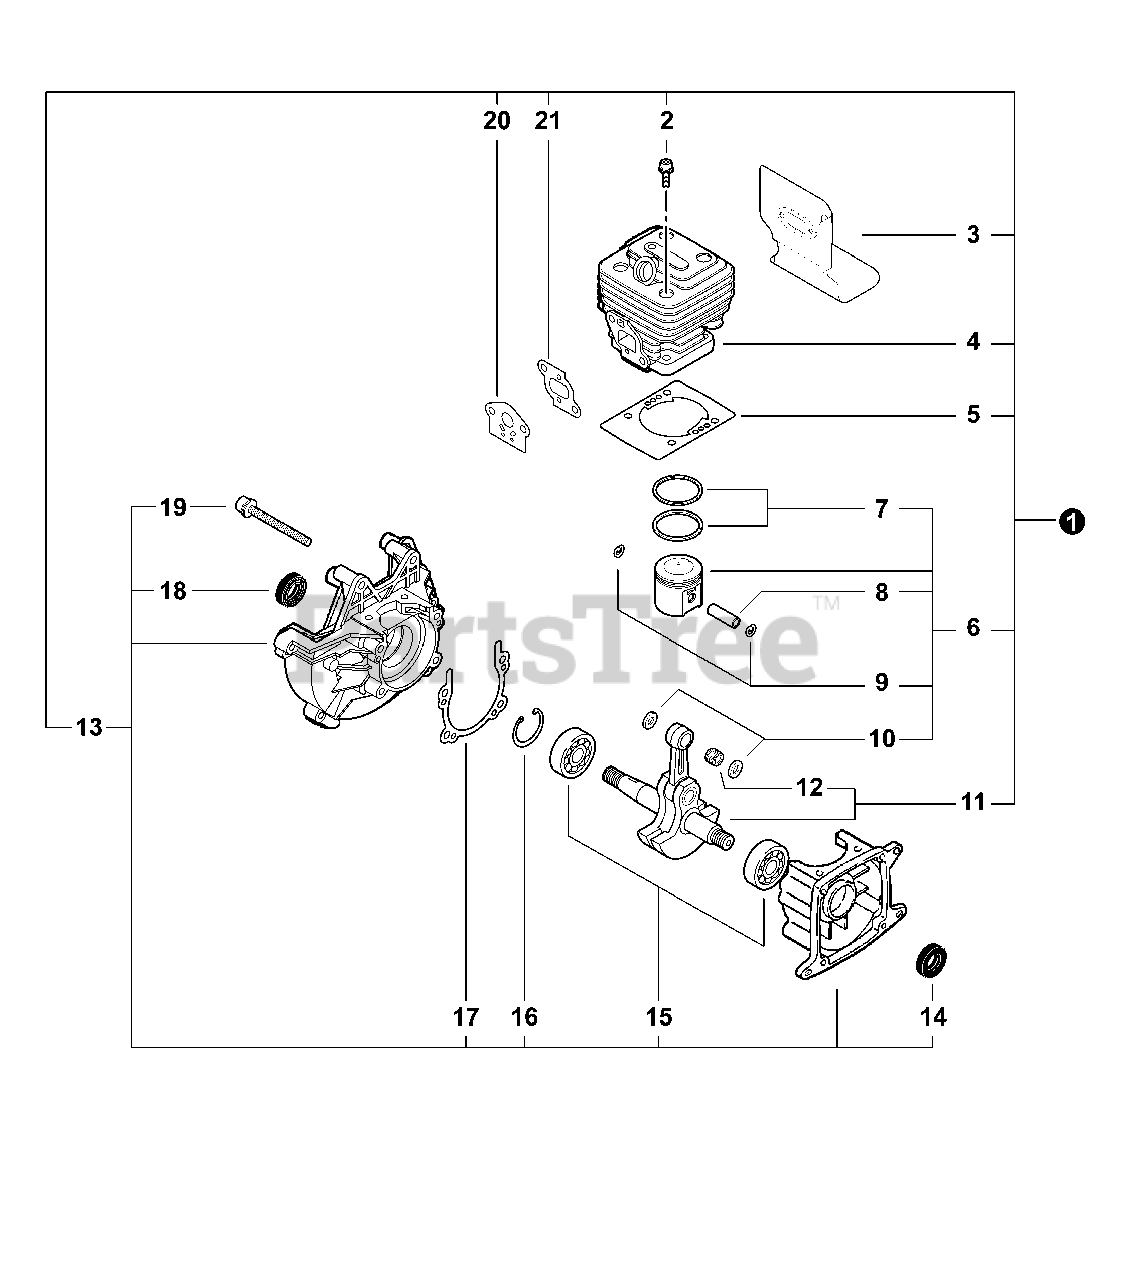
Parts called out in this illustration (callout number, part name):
1	SHORT BLOCK -- SB1060
2	SCREW - 5×22
3	SHIELD, EXHAUST
4	CYLINDER
5	GASKET, CYLINDER
6	PISTON KIT
7	RING, PISTON
8	PIN, PISTON
9	RING, RETAINING
10	SPACER, PISTON
11	CRANKSHAFT ASY
12	BEARING, NEEDLE
13	CRANKCASE KIT
14	SEAL, OIL - 12
15	BEARING, BALL - 6001
16	RING, RETAINING - 28
17	GASKET, CRANKCASE
18	SEAL, OIL
19	SCREW - 5×25
20	GASKET, INTAKE
21	GASKET, INTAKE
